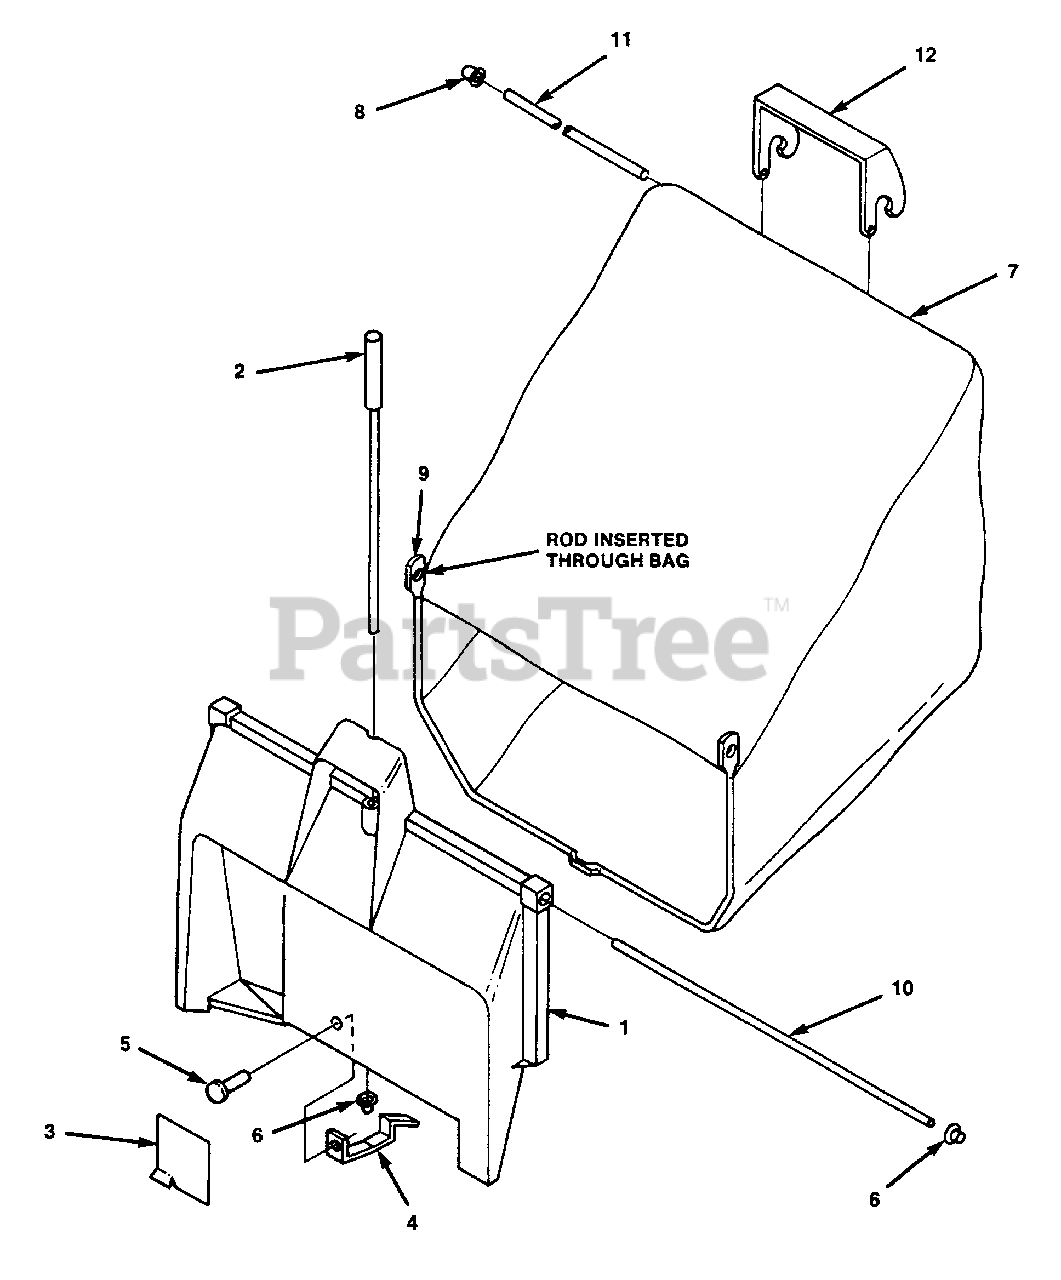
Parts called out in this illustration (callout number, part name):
1	ADAPTOR- Bag
2	ROD- Latch release
3	DEFLECTOR
5	RIVET- Pop 5/32 x 3/8"
7	GRASS BAG
9	ROD- Bag support
10	ROD- Bag hinge
11	ROD- Upper bag
12	HANDLE- Upper bag
